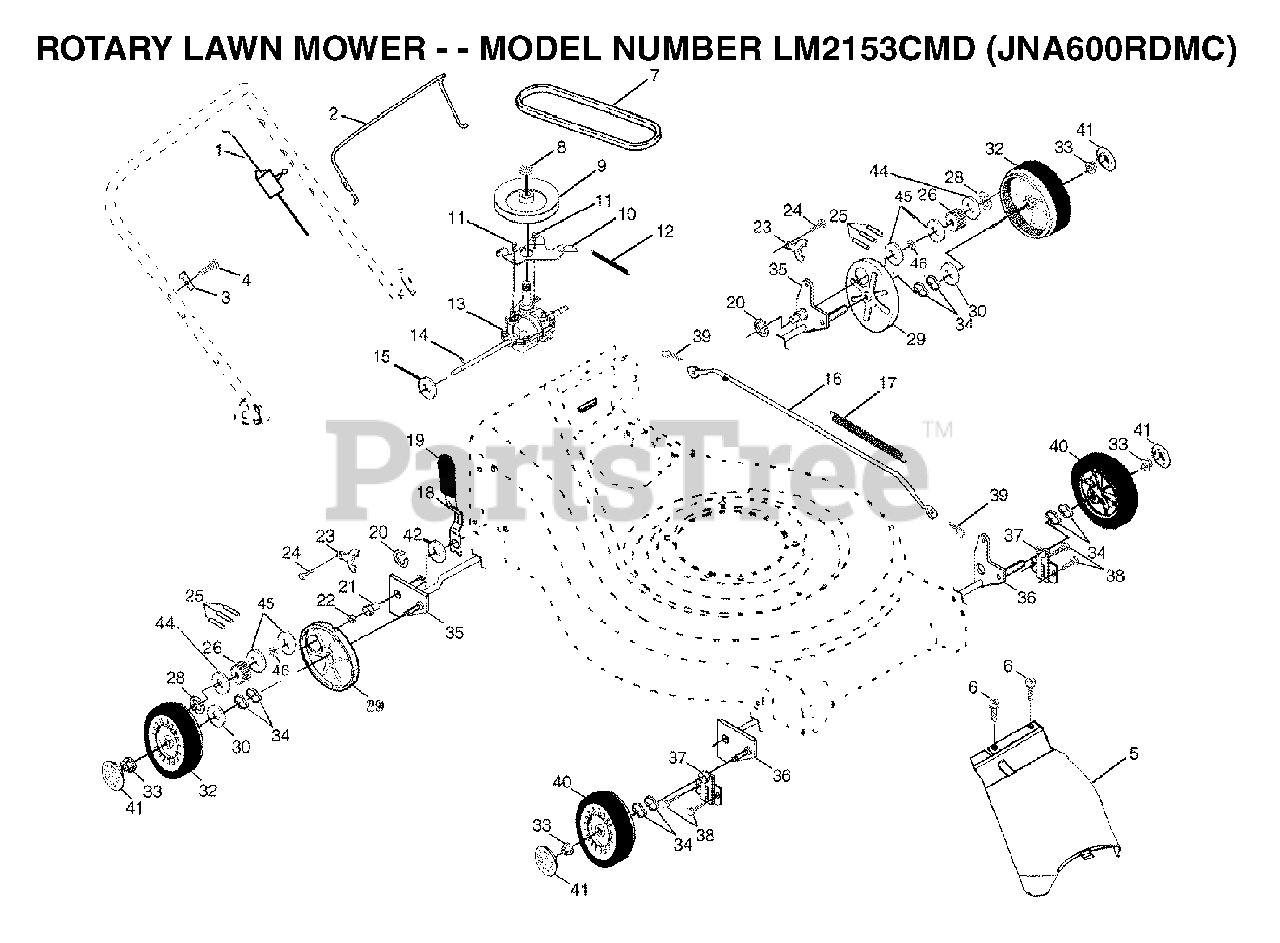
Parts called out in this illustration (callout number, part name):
1	DRIVE CABLE
2	BAIL.CONT.DR.21.RWGD.BLACK
3	DOWNSTOP BRACKET
4	SCREW.HEX.HEAD.WASHER.10-16
5	DRIVE COVER
8	FLANGED LOCKNUT 3/8-16 ZINC
13	TRANSMISSION ASM. (WALK)
14	PIN.SPRING.THRUST
15	THRUST WASHER
16	ROD CONNECTING
17	SPRING
18	SPRING
19	KNOB
21	RP BEARING SUPPORT
22	BEARING, BALL
23	BRACKET
26	DRIVE PINION
28	E-RING 7/16 RE
29	DUST COVER, WHEEL
30	WASHER FLUT
32	WHEEL, 9 X 2
33	HEX FLANGE LOCKNT
34	WAVE WASHER
35	SHAFT ASSY
36	SHAFT ASSY
37	RETAINER.FRONT.SHAFT
39	RETAINER CLIP
40	WHEEL ASMBLY FRONT
41	CAP.HUB.ARC.SPOKE.8".LP
44	WASHER
45	BELLEVILLE WASHER
